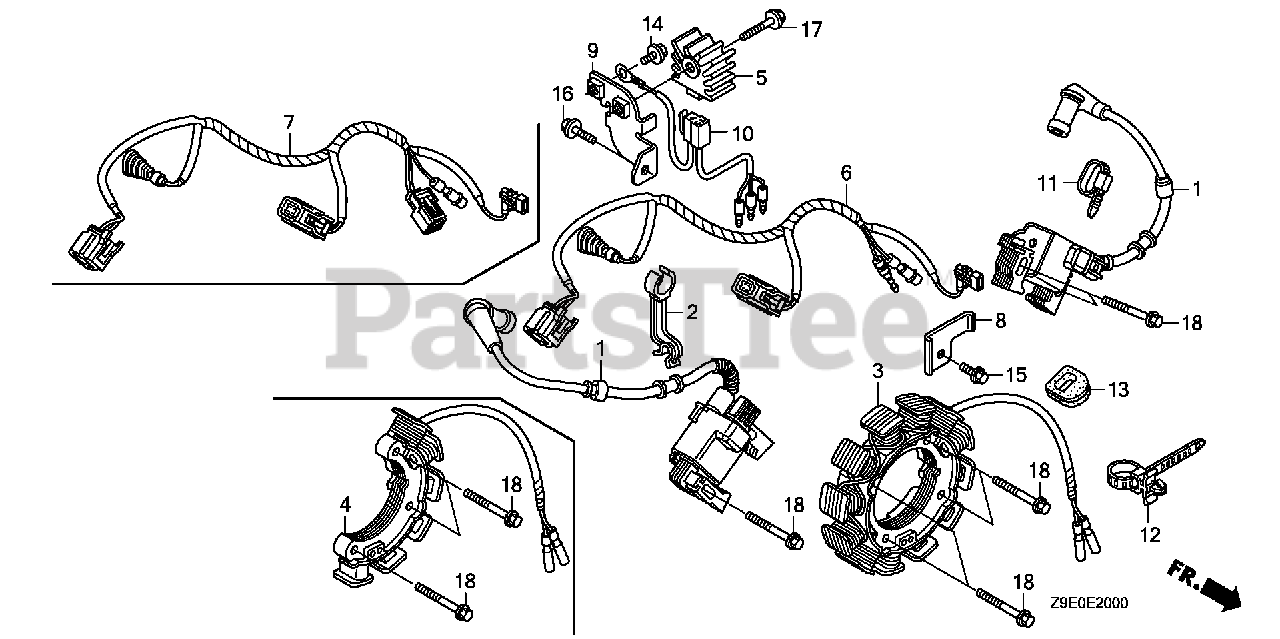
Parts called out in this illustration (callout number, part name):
1	COIL ASSY., IGNITION
2	CLAMP, IGNITION WIRE
3	COIL ASSY., CHARGE (17A)
6	WIRE HARNESS ASSY., ENGINE
8	BRACKET, HARNESS
11	BAND, WIRE (95MM)
12	STRAP, CABLE (105MM) *NH1* (Honda Code 1685536). (BLACK)
13	GROMMET, CORD
15	BOLT, FLANGE (6X12) Use up to Engine SN 1543277.
18	BOLT, FLANGE (6X32)
